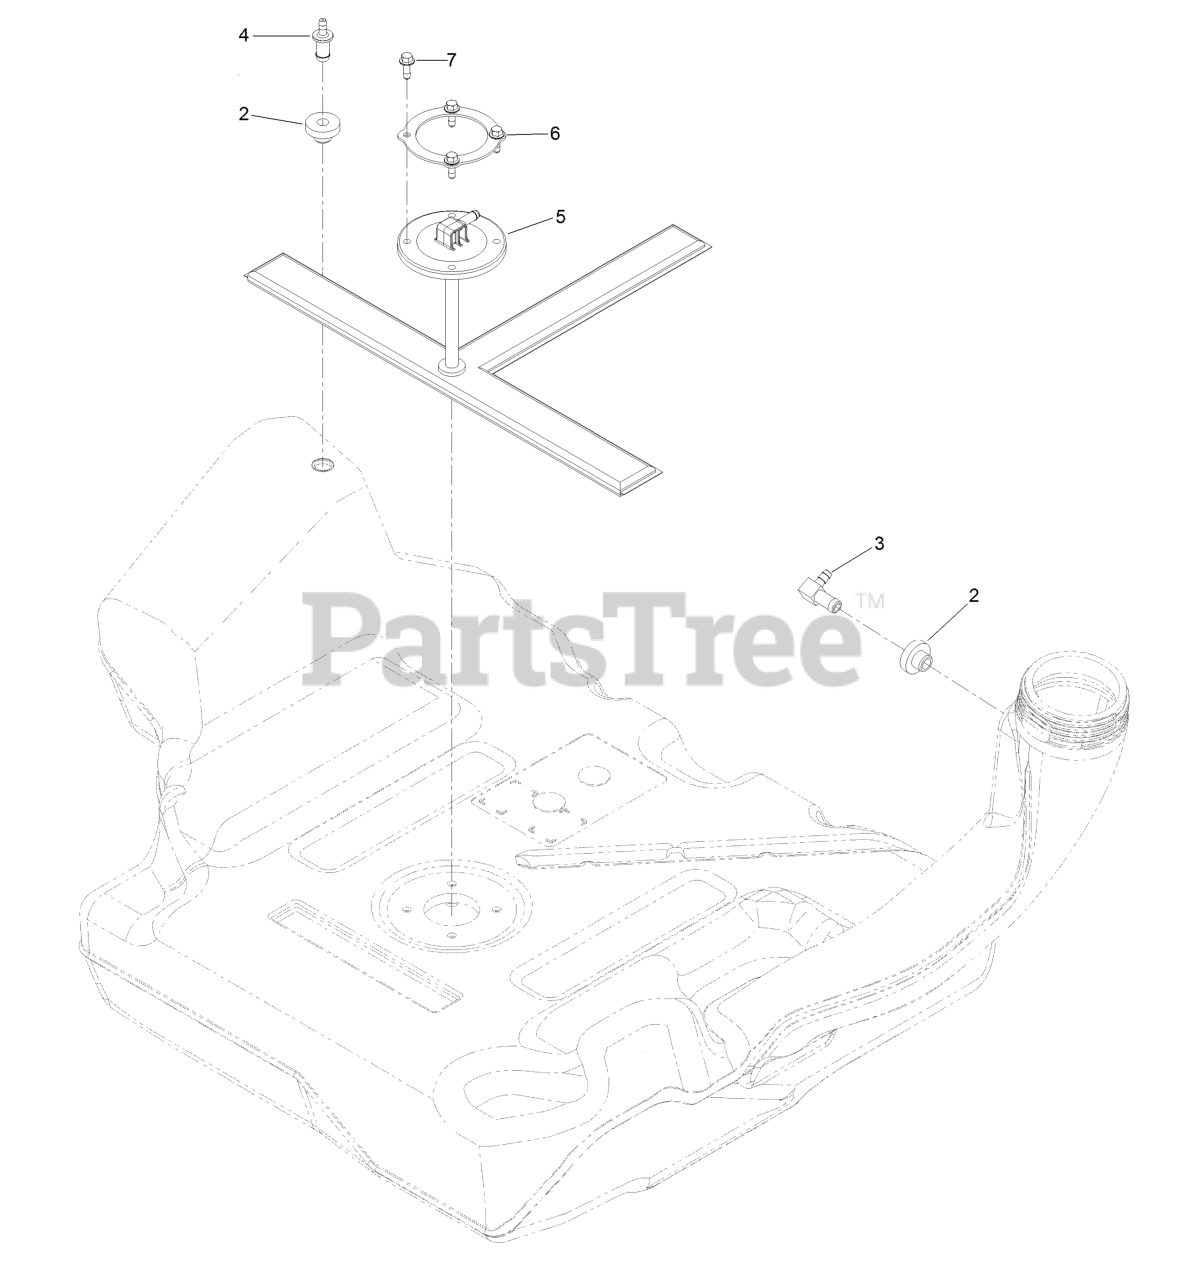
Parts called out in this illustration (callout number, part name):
2	Bushing
3	Fitting-90 DEG
4	Fitting-Orifice, Straight
5	Pickup-Fuel
6	Ring-Retainer
